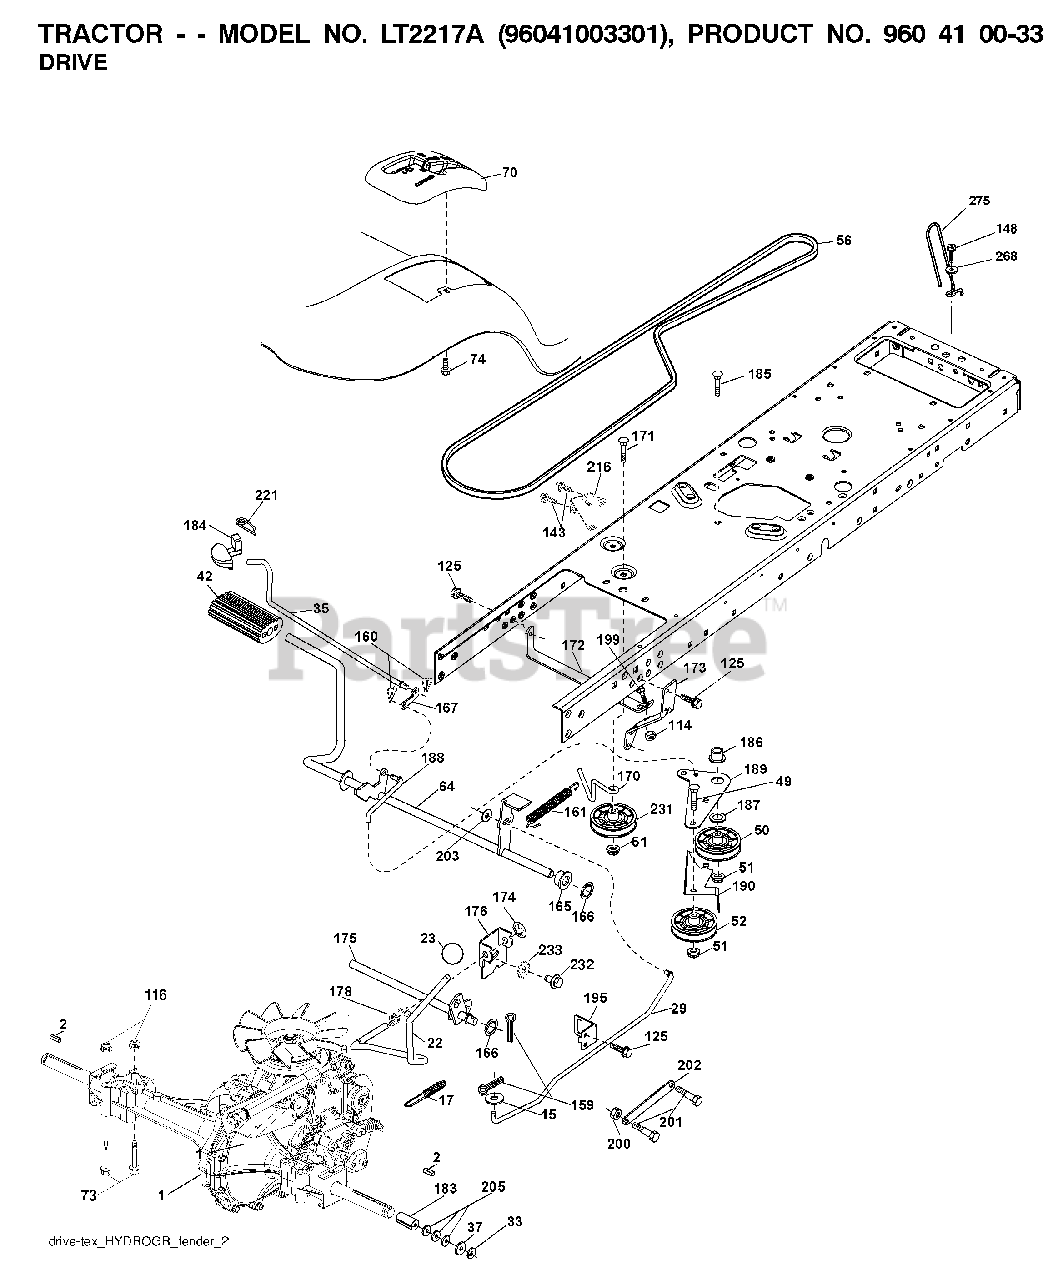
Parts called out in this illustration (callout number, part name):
2	SQUARE KEY
17	SPRING.BRAKE.HG3000/3500
22	ROD.SHIFT.FENDER.TLT.2006
23	KNOB.DUCKHEAD.1/2
29	ROD.BRAKE.HG-0510
33	E-RING LT
35	ROD.BRAKE.PARKING.LT.T
42	PEDAL COVER T
49	BOLT
50	IDLER.FLAT.910.OFFSET
51	NUT LOCK FLG 3/8-16 UNC
52	IDLER.V-GROOVE.910.OFFSET
64	SHAFT.ASM.PEDAL.BRAKE.
70	CONSOLE.SHIFT.STL.HYD.BLACK
73	BOLT HEX 5/16-18 GR 5
74	SCREW.HI-LO.CONSOLE
114	NUT.71038.31-18.HEX.NYLOCK
116	NUT LOCK HEX FLANGE 5/16-18
125	SCREW
148	SCREW, 3/8-16X3/4
159	COTTER PIN
160	RETAINER CLIP
161	SPRING.RETURN.CLUTCH.2006
165	BUSHING.SHAFT.BRAKE.HAND
166	NUT.PUSH.625.2006
167	LATCH.BRAKE.SPRING
170	KEEPER.V-IDLER.CENTER.
172	STRAP.TRQ.LH.FS.HG0510
173	STRAP TORQUE RH
174	NUT.PUSH.500.2006
175	SHAFT.ASM.SHFT.HG0510/
176	ARM.CLEVIS.ROD.SHIFT
178	SPRING.SHIFT.GT2006
183	SPACER AXLE
184	HANDLE.PAKRING.BRAKE.
186	SPACER.RETAINER
187	WASHER 12/32X2X10GA
188	LINK.CLUTCH.GROUND.DRIVE
189	BELLCRANK.GROUND.DRIVE.TEX.
190	KEEPER.BELLCRANK.DRIVE
195	BRKT.ROD.BRAKE.18/20/2
199	BOLT
200	NUT.CENTERLOCK.5/16-
201	BOLT SHOULDER 5/16-18 UNC
202	LINK TRANS
203	WASHER
216	BRACKET.PULLEY.IDLER.W/TEX
221	RETAINER.SPRING.CLIP.H
231	IDLER.V-GROOVE.1.688.OFFSET
232	BOLT FIN HEX 7/16-14 X 1
233	WASHER SERRATED
268	WASHER
